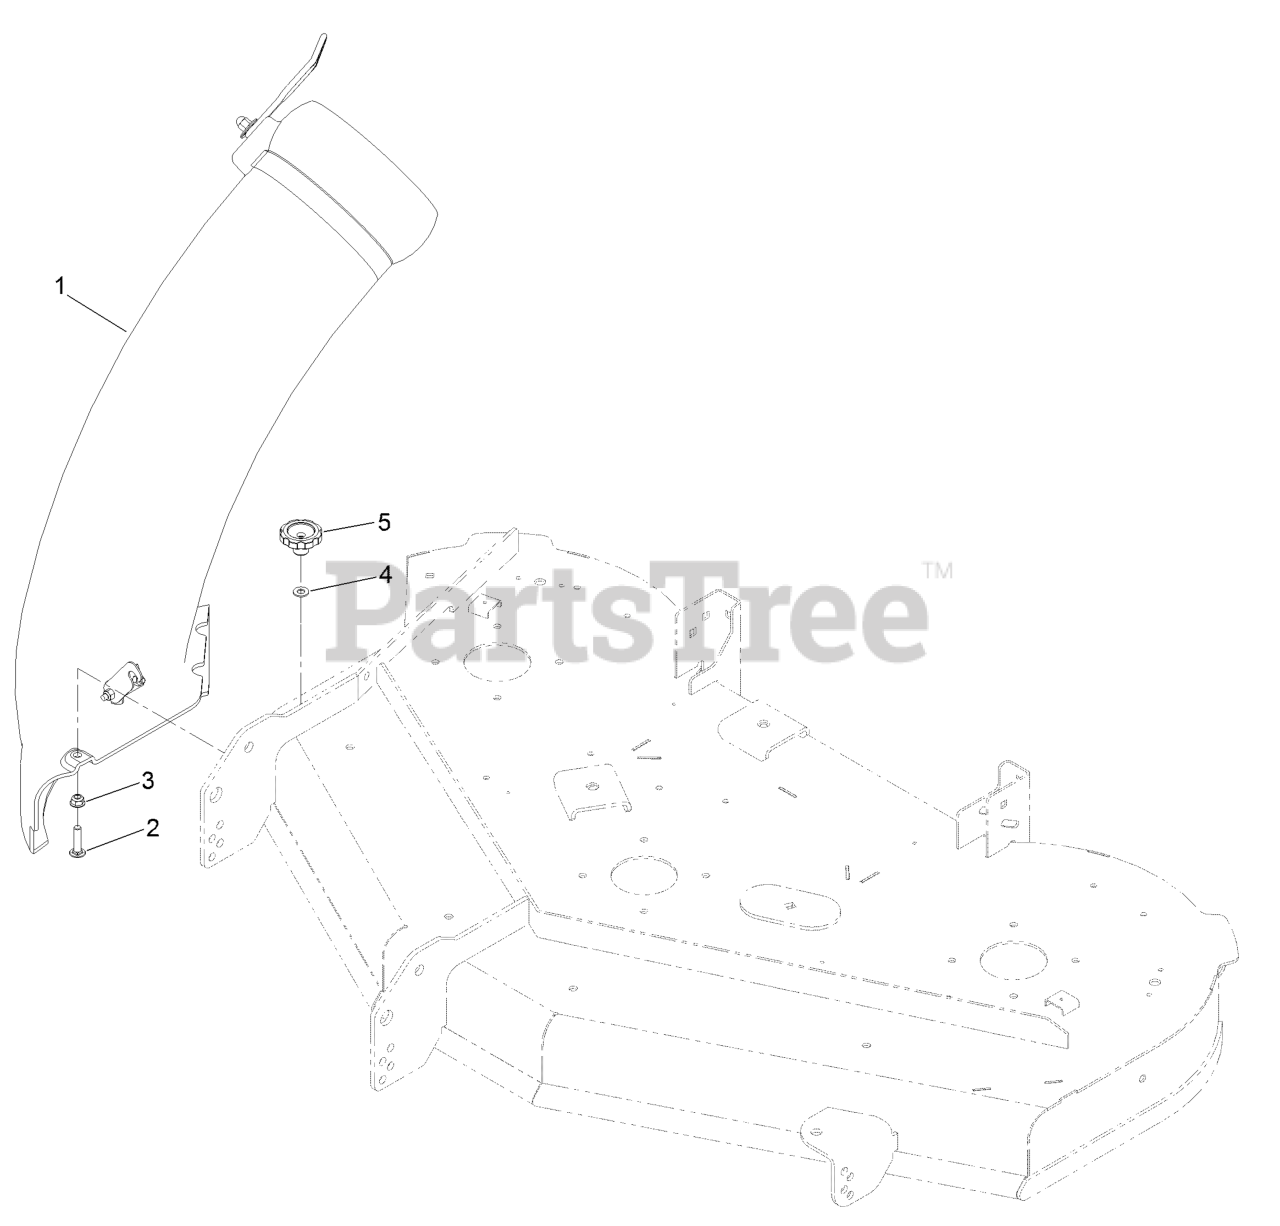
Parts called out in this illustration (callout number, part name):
1	50 INCH CHUTE ASM
2	SCREW-CARR
3	NUT-HF, NI
4	WASHER-PLAIN
